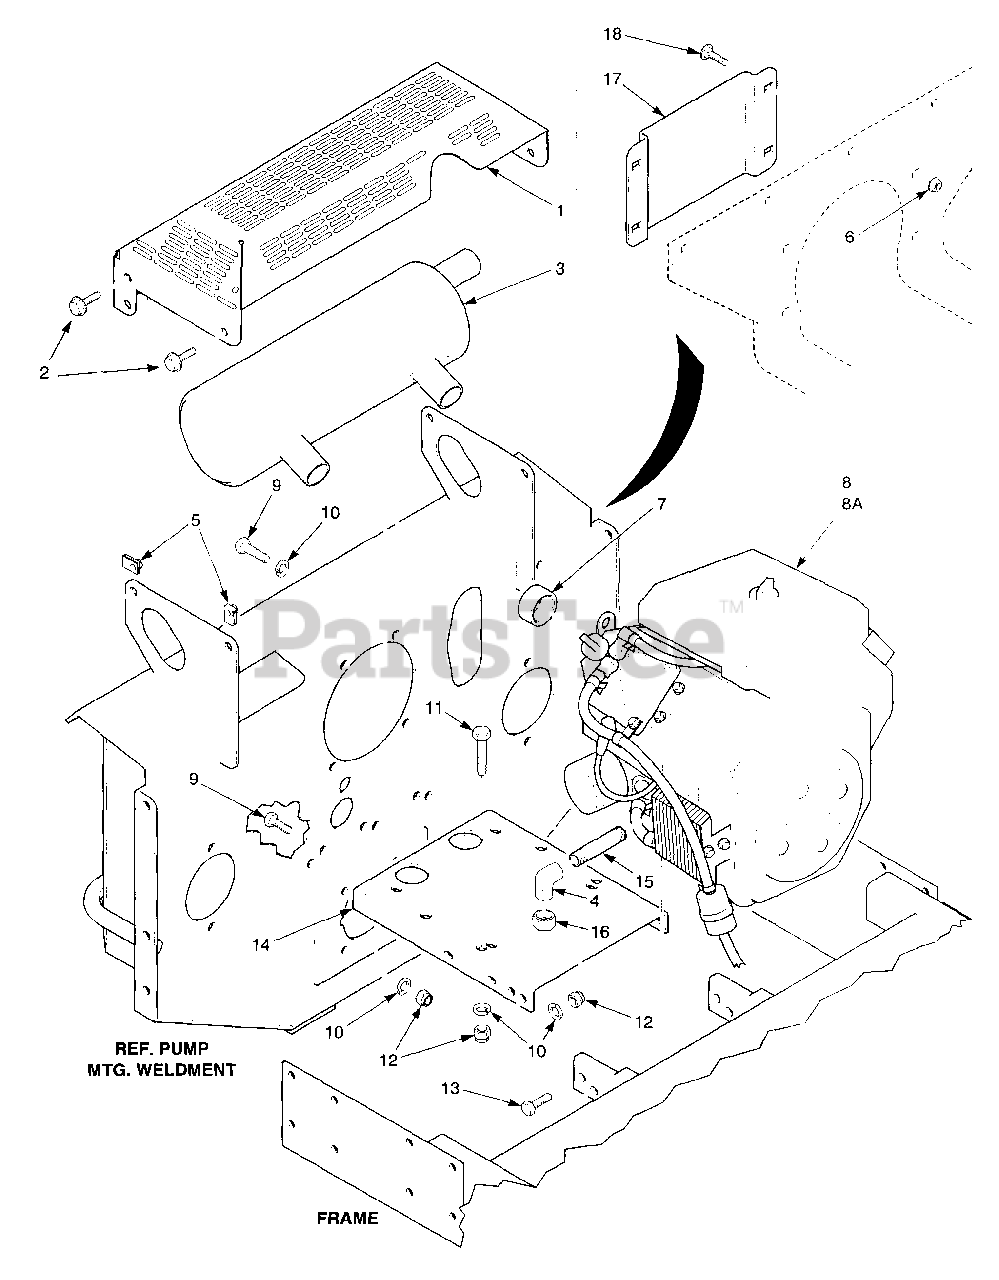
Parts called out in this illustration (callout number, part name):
1	Muffler Guard
2	Screw, Hex Serrated Flange 1/4-20 x 3/4"
3	Muffler, Part Of Engine
4	Screw, #10-16 x 1/2"
5	U-Nut, 1/4-20
6	Exhaust Elbow
7	Spacer, Engine (Kohler)
8	Engine, Kohler 22 CH
9	Bolt, Hex Head 3/8-16 x 1"
10	Lockwasher, 3/8" Spring
11	Bolt, Hex Head 3/8-16 x 1-3/4"
12	Nut, Hex Elastic Stop 3/8-16
13	Bolt, Hex Head 3/8-16 x 1-1/4"
14	Plate, Engine Mounting
15	Extension, Oil Drain 2"
16	Pipe Cap, Hex 3/8"
17	Rear Cover
18	Bolt, Carriage 5/16-18 x 3/4"
